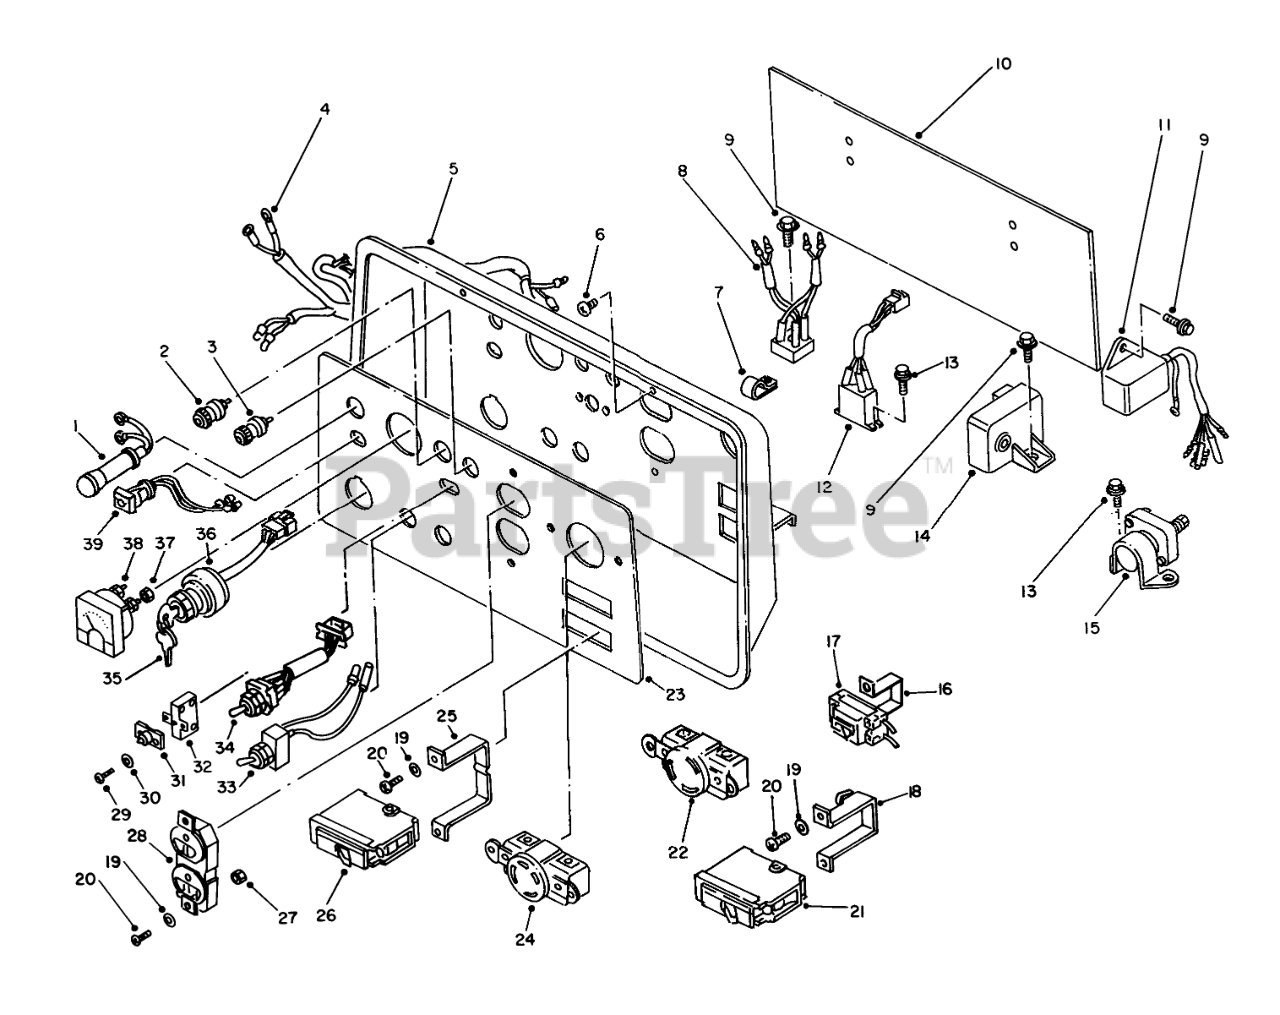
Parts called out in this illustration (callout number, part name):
1	Holder Assembly Lamp
2	TERMINAL (-)
3	Terminal
4	Harness-Control (110V/220V)
5	Panel-Control
6	Screw
7	Clamp
8	RECTIFIER ASM
10	Insulato Panel
11	Unit-Fuel/Oil Interlock
12	Relay
13	SCREW-HHF
14	Unit-Slow Down
15	RELAY ASM
16	Holder-Breaker
17	Breaker-Circuit (15A2P)
18	Holder-Breaker
19	Washer
20	Screw
21	Breaker-Circuit (30A)
22	Receptacle (125V, 30A)
23	Plate-Panel
24	Receptacle
25	Holder-Breaker
26	CIRCUIT BREAKER
28	Receptacle
29	Screw
30	Washer
32	Circuit Breaker DC
33	Switch-Auto Idle
34	Switch-Remote Select
36	Switch Assembly-Engine (Incl. Ref. #35)
38	Meter-Voltage(150V/300V)
39	Lamp-Oil Level
